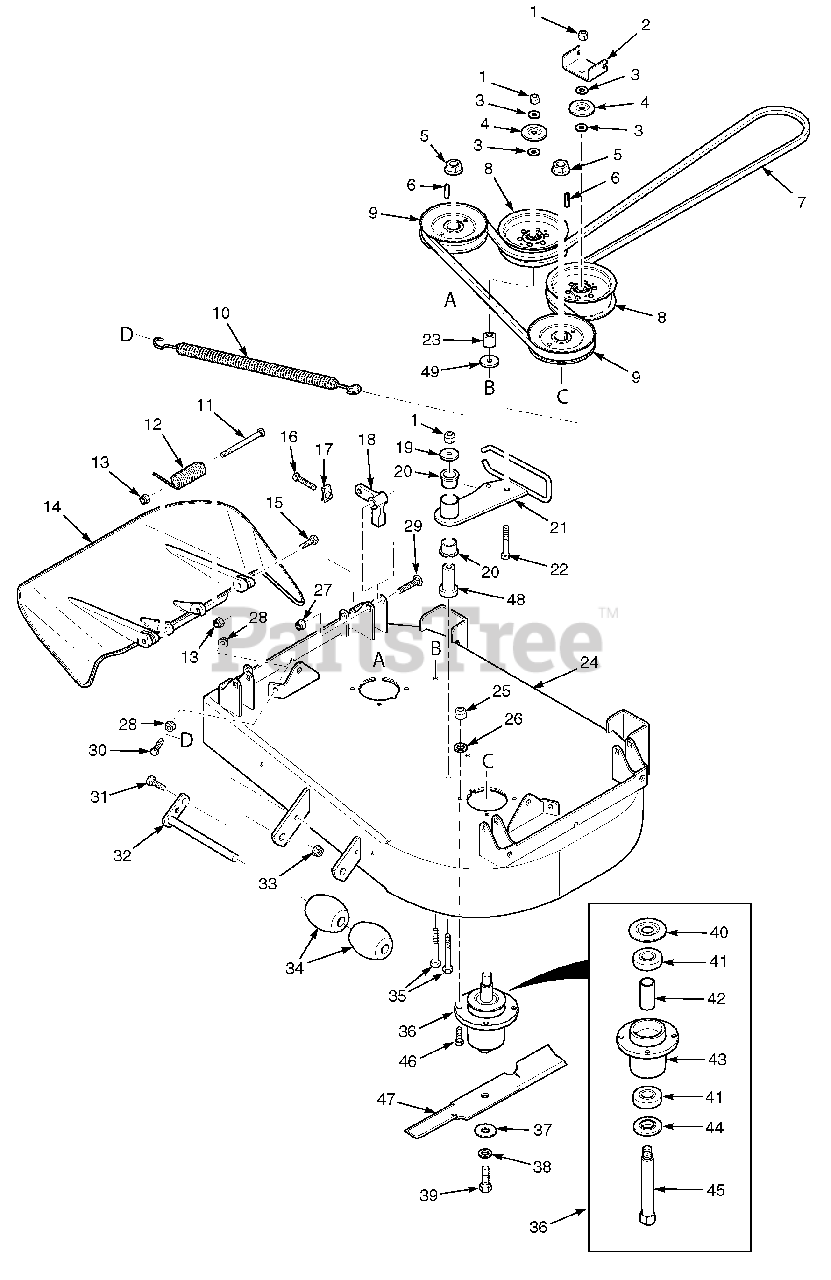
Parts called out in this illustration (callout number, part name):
1	Nut, Elastic Stop 3/8-16
2	Bracket, Belt Guide
3	Flatwasher, 3/8-.391 x .938 x .105
4	Dust Shield
5	Nut, 3/4-16 Spiral Lock
6	Key, 1/4 x 1/4 x 1-1/4"
7	Belt, Cutter Deck
8	Pulley, 5" Idler
9	Pulley, 5.73" OD - 25mm Bore
10	Spring, Idler
11	Bolt, Hex Head 5/16-18 x 4-3/4"
12	Spring, Discharge Chute
13	Nut, Elastic Stop 5/16-18
14	Discharge Chute Assembly
15	Bolt, Hex Head 5/16-18 x 1-3/4"
16	Bolt, Hex Head 3/8-16 x 2" Special Lock
17	U-Nut, 3/8-16
18	Lever, Deck Level
19	Flatwasher, 3/8-.406 x 1.50" x 7 Ga.
20	Bearing
21	Idler Arm
22	Bolt, Hex Head 3/8-16 x 2-1/2"
23	Spacer
24	Cutter Deck w/Decals, SFZ36
25	Nut, Elastic Stop 5/16-18
26	Lockwasher, 5/16 Spring
27	Nut, Elastic Stop 7/16-14
28	Nut, Serrated Flange 3/8-16
29	Bolt, Carriage 7/16-14 x 2-1/4"
30	Bolt, Hex Head 3/8-16 x 1-1/2" Gr.8
31	Bolt, Hex Head 5/16-18 x 1"
32	Shaft Weldment
33	Nut, Serrated Flange 5/16-18
34	Wheel, Anti-Scalp
35	Bolt, Hex Head 3/8-16 x 3-1/2"
36	Spindle Assembly
37	Flatwasher, 5/8-11 x 1-1/2"
38	Lockwasher, 1/2 Spring
39	Bolt, Hex Head 5/8-11 x 1-1/2"
40	Debris Shield
41	Bearing
42	Spacer, Bearing
43	Spindle Housing Assembly
44	Protector, Bearing
45	Shaft, Spindle
46	Bolt, Hex Head 5/16-18 x 1-1/2" Gr.8
47	Cutter Blade, 48"
48	Pivot, Idler
49	Flatwasher, 3/8-.406 x 2.25" x .1875
